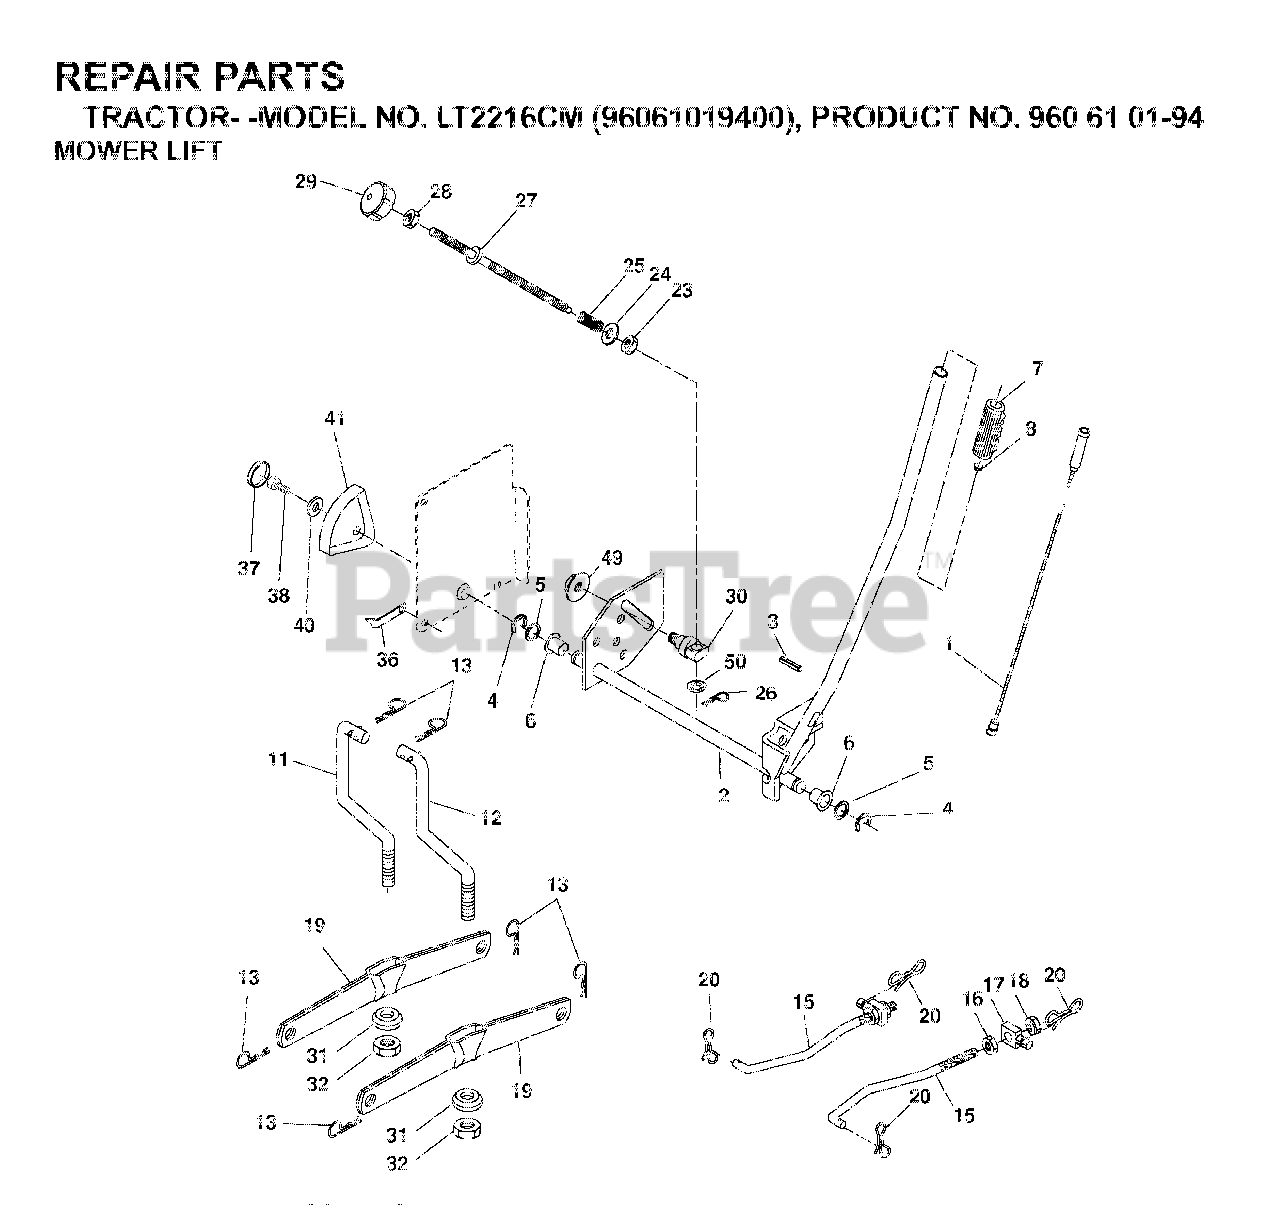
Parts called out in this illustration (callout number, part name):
4	RETAINING RING LT
6	BEARING.NYLON
7	GRIP HANDLE
8	PLUNGER BUT KIT
11	LINK
12	LINK
13	RETAINER-SPRNG RB
15	LINK.SUSPENSION.FRONT
16	NUT
18	NUT
19	ARM.REAR.SUSPENSION
20	PIN.COTTER.7/16.BOW TI
25	SPRING**
26	RETAINER CLIP
27	ROD ADJ LIFT
28	NUT
29	KNOB INF 3/8-16
31	BEARING.PIVOT.LIFT
32	NUT CROWNLOCK 3/8-24
36	POINTER, HEIGHT INDICATOR
37	PLUG,HOLE
38	SCREW 5/16-18X1
41	HEIGHT INDICATOR
49	NUT
50	NUT PUSH M
